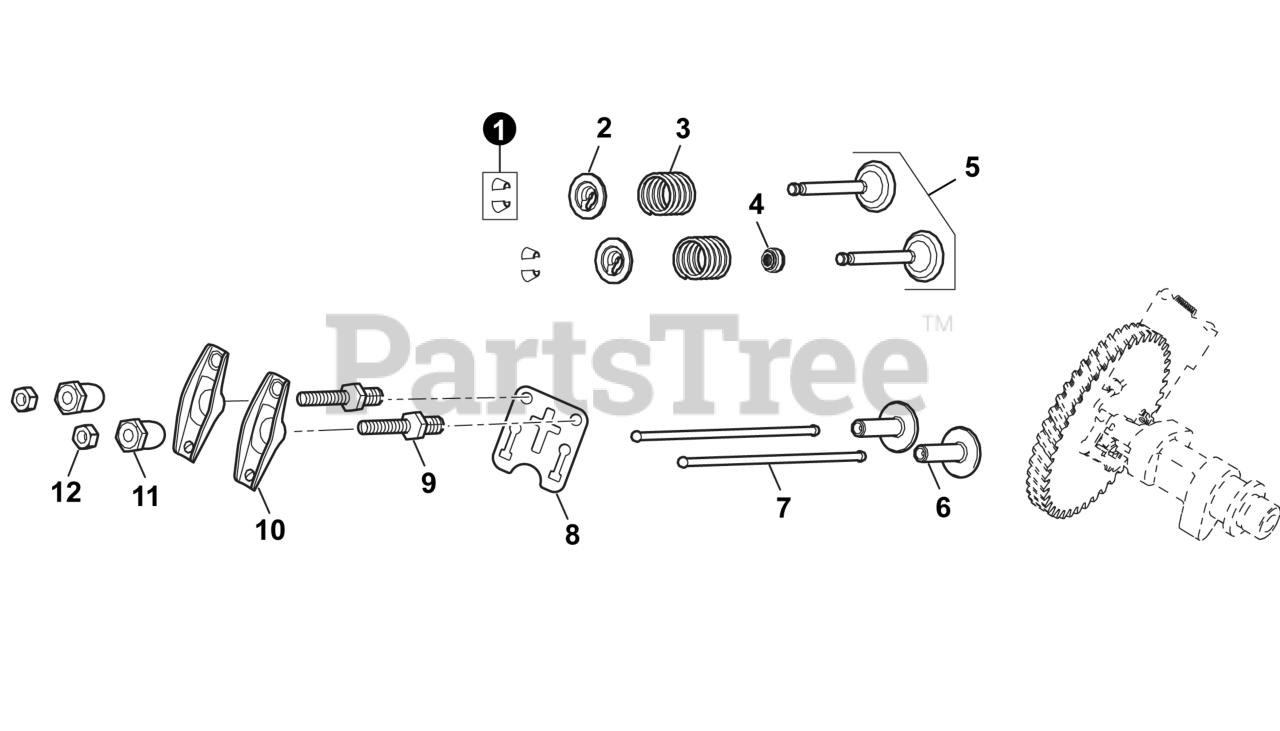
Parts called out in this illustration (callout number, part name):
1	CLAMP, VALVE LOCK
2	SEAT, VALVE SPRING
3	SPRING, VALVE
4	SEAL, GUIDE
5	VALVES SET, INTAKE/EXHAUST
6	TAPPET, VALVE
7	ROD, PUSH
8	PLATE, LIFTER STOPPER
9	BOLT, ROCKER SHAFT
10	ARM, ROCKER
11	NUT, VALVE ADJUSTING
12	NUT, VALVE LOCK
